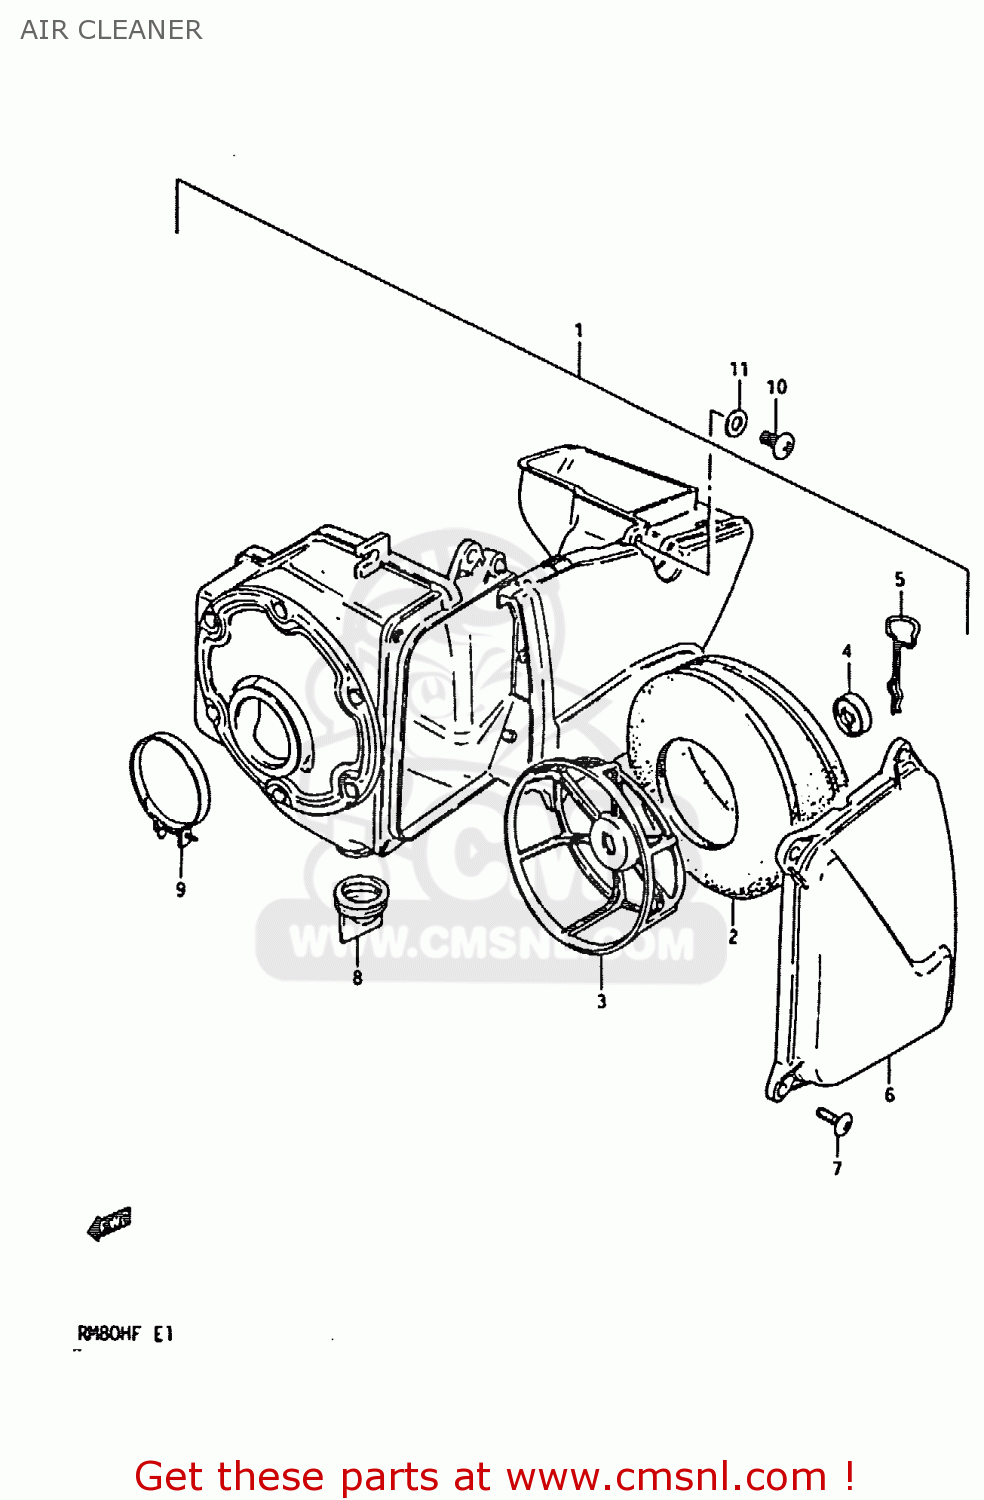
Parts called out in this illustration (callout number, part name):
1	CLEANER ASSEMBLY,AIR
2	FILTER,AIR CLEANER
3	HOLDER,AIR CLEANER
4	WASHER
5	PIN,SNAP
6	CAP,AIR CLEANER
7	SCREW M5X12 DIN 7985/N
8	HOSE,AIR CLEANER DRAIN
9	CLAMP
10	SCREW
11	WASHER
